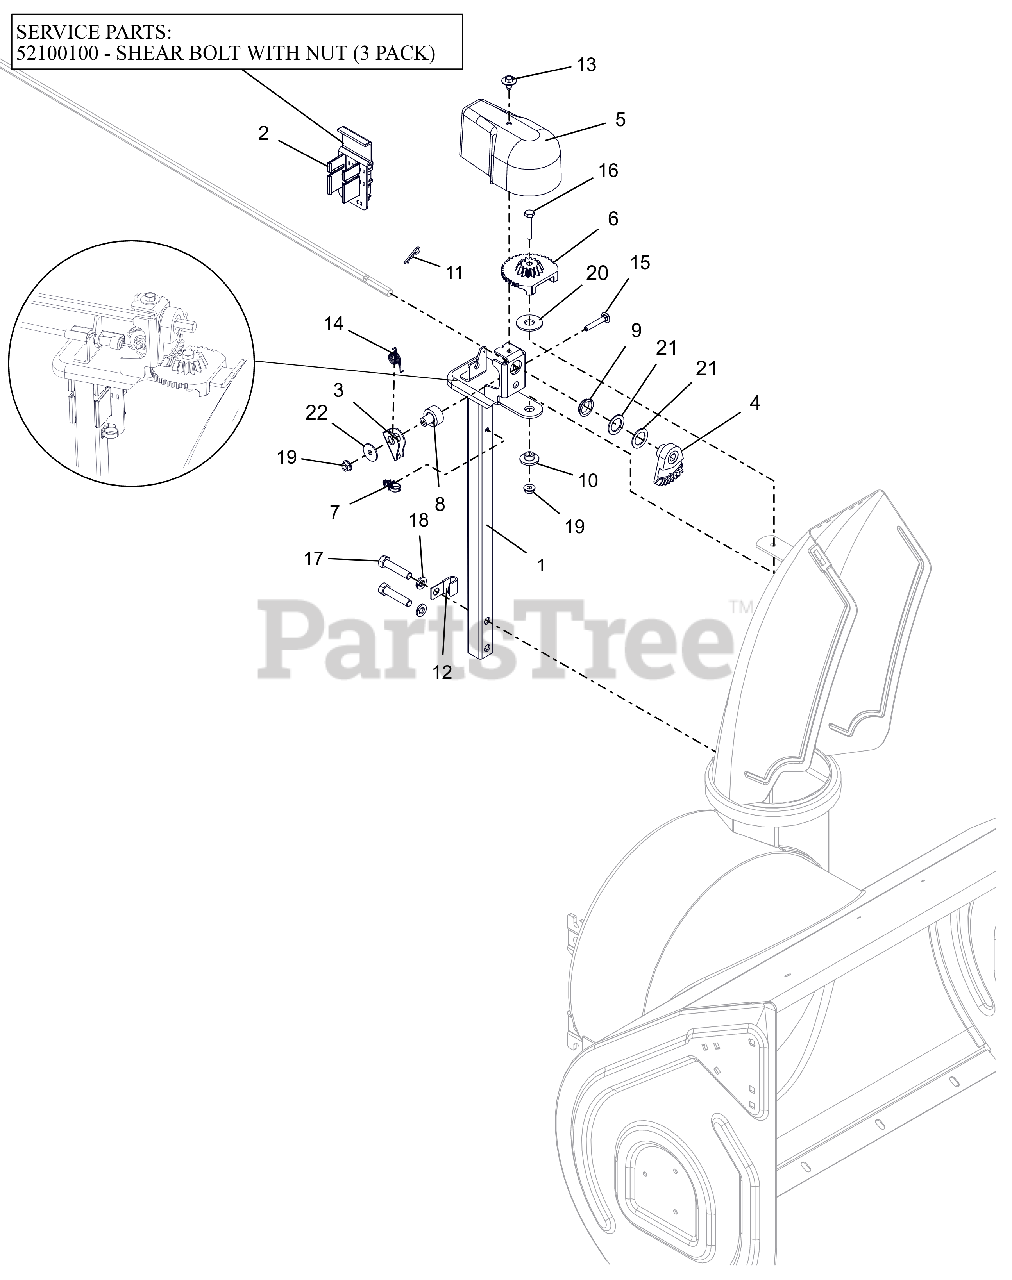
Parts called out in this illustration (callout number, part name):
1	PEDESTAL, CHUTE - QUICK STICK
2	HOLDER W LARGE SHEAR BOLT /NUT
2	SHEAR BOLT SERVICE ASSEMBLY
3	ARM, LOCKING
4	GEAR, CHUTE-ACTUATION
5	COVER, CHUTE GEAR
6	GEAR, CHUTE
7	CLIP, CABLE GUIDE
8	BUSHING, LOCK ARM
9	BUSHING, POLYLINER-.75 SNAPIN
10	BSHG-FLG .265X.477X.375X1.00
11	PIN, HAIR #213 .08X1.19 ZCC
12	J-CLAMP
13	SCR, TAP .25-20X.50 LG HWH ZCC
14	SG-TORS
15	BLT, RHSN .25-20X1.50 G5 ZCC
16	BLT, HEX .25-20X1.50 G5 ZCC
17	BLT, HEX .38-16X1.75 G5 ZCC
18	WSHR,LK-REG .375X.094 ZCC
19	NUT-LK-CTR-FLG .25-20 ZC120
20	WSHR-FLT-NYL .515X1.375X.093
21	WSHR, FLT .754X1.125X.062 ZCC
22	WSHR,FLT .281X1.000X.063 ZCC
